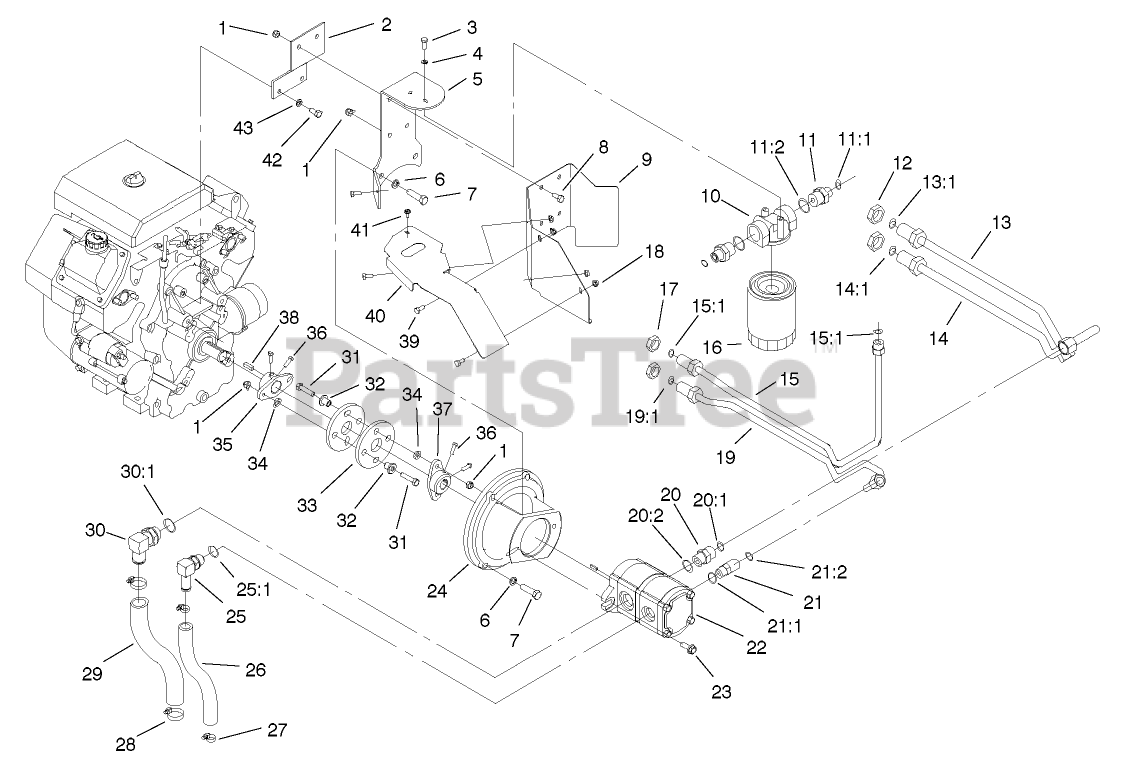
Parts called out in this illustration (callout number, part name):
1	NUT-LOCK, NI
2	BRACKET-SUPPORT, OIL FILTER
3	SCREW-HH
4	WASHER-LOCK
5	BRACKET-SUPPORT, OIL FILTER
6	WASHER-LOCK
7	SCREW-HH
8	SCREW-HH
9	SHIELD-HEAT, FILTER
10	HEAD-FILTER
11	FITTING-STR
11:1	O-RING
11:2	O-RING
12	NUT-LOCK, BULKHEAD
13	HYD TUBE ASM
13:1	O-RING
14	HYD TUBE ASM
14:1	O-RING
15	HYD TUBE ASM
15:1	O-RING
16	FILTER-OIL
17	NUT-BULKHEAD
18	NUT-LOCK, NI
19	HYD TUBE ASM
19:1	O-RING
20	FITTING-STRAIGHT
20:1	O-RING
20:2	O-RING
21	FITTING-ELBOW-90 DEG
21:1	O-RING
21:2	O-RING
22	PUMP-GEAR, HYD
23	SCREW-HHF
24	Mount-Pump
25	FITTING
25:1	O-RING
26	HOSE-HYD
27	CLAMP-HOSE
28	CLAMP-HOSE
29	HOSE-HYD
30	FITTING-HYD, 90 DEG
30:1	O-RING
31	SCREW-HH
32	SPACER
33	COUPLING-RUBBER
34	WASHER-PLAIN
35	HUB-ENGINE
36	SCREW-SQH
37	HUB-PUMP
38	KEY-SQUARE
39	SCREW-HH
40	SHIELD-HEAT
41	SCREW
42	SCREW-HH
43	WASHER-LOCK
